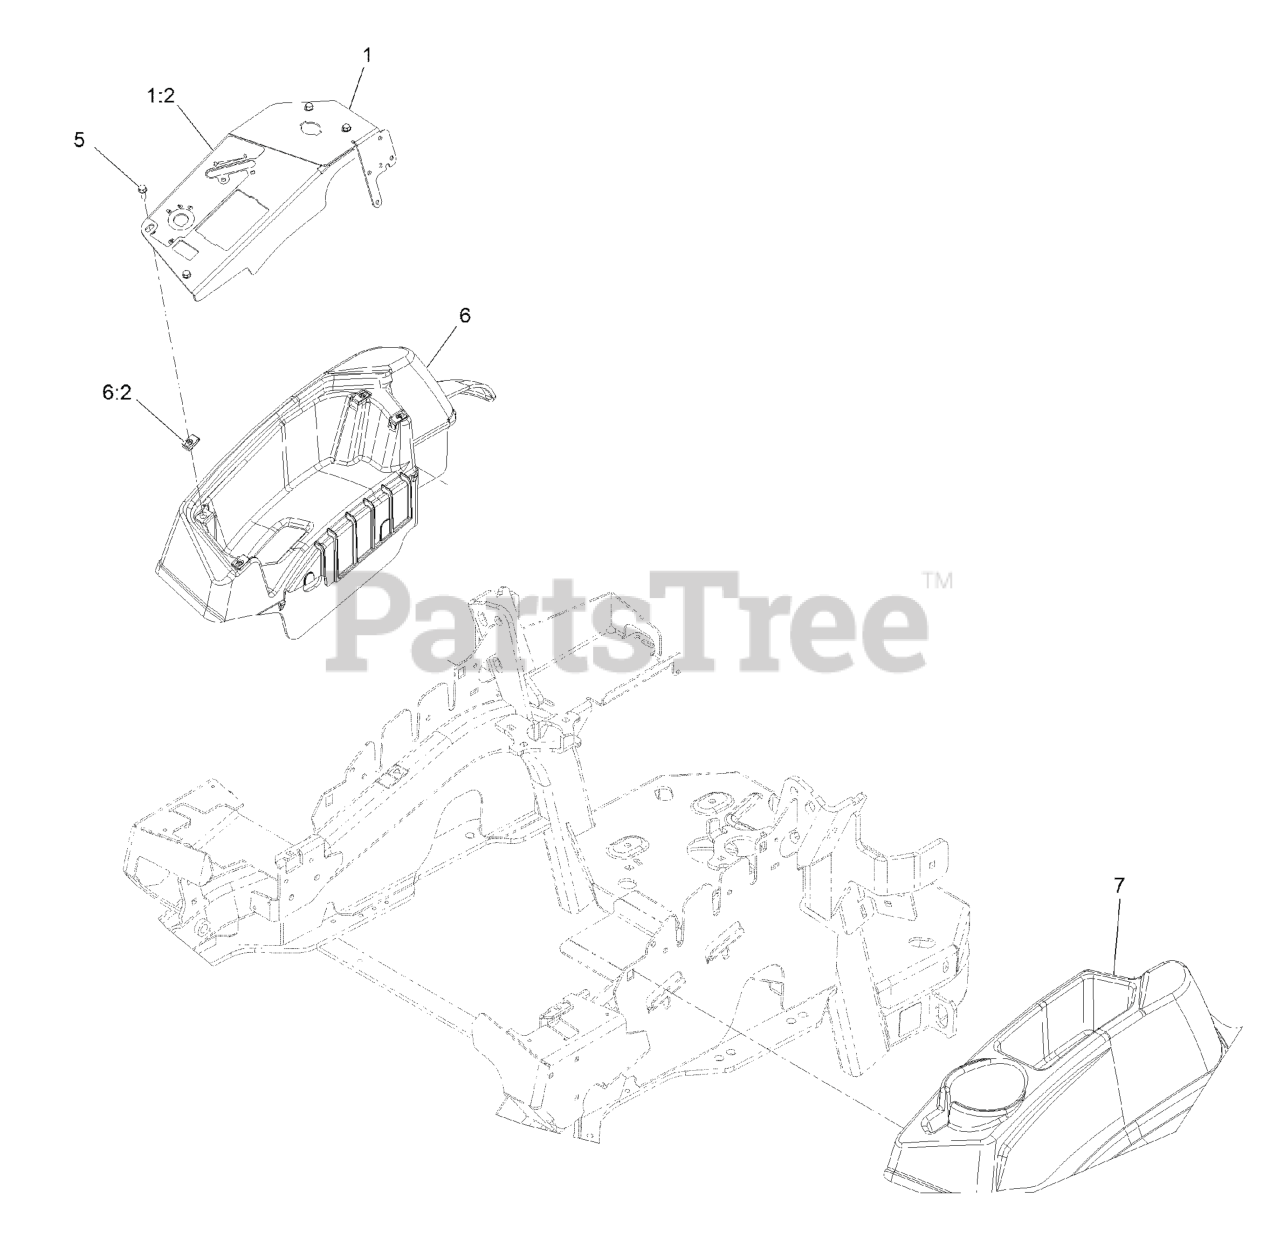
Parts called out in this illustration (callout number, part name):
1	PANEL-CONTROL W/DECAL SHM-EFI
1:2	DECAL-CONTROL PANEL-EFI
5	SCREW-HWH
6	CONSOLE,RH AS ASM
7	CONSOLE, LH AS
